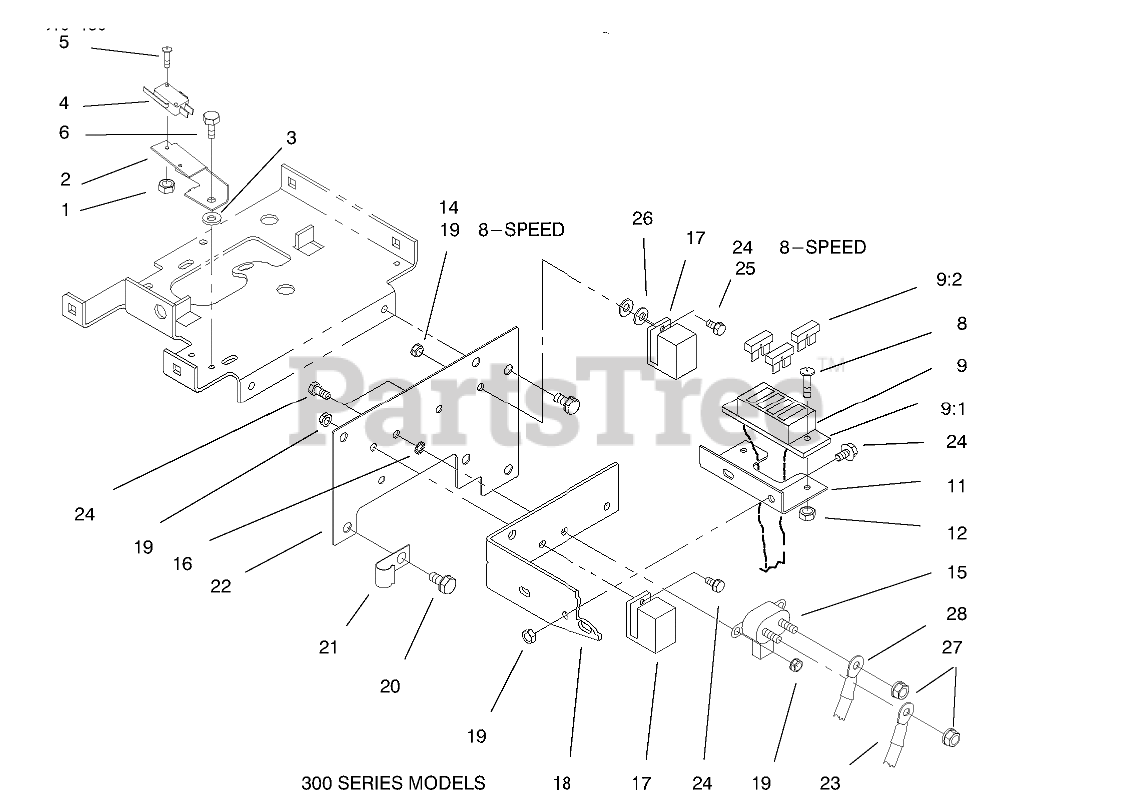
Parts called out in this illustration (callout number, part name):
1	NUT-HEX
2	BRACKET-SWITCH
3	WASHER-LOCK, INTERNAL
4	SWITCH
5	SCREW-PHL 4-40X1 1/4
6	SCREW-HWH
8	SCREW-PAN
9	WIRING HARNESS & DIA
9:1	FUSE-HOLDER 4 WAY
9:2	FUSE-10 AMP
9:2	FUSE-BLADE, 25 AMP
9:2	FUSE-BLADE, 20 AMP
9:2	FUSE-30 AMP
11	FUSE HOLDER
12	Nut
15	Solenoid
16	WASHER-LOCK/EXT
17	RELAY
18	BRACKET-BELT (BLACK)
19	NUT-LOCK, NI
20	Bolt
21	CLIP
22	PLATE-FRONT HOODS (BLACK)
23	ASSY WIRE
24	SCREW-HHF
27	NUT-KEPS
28	CABLE-BLACK
